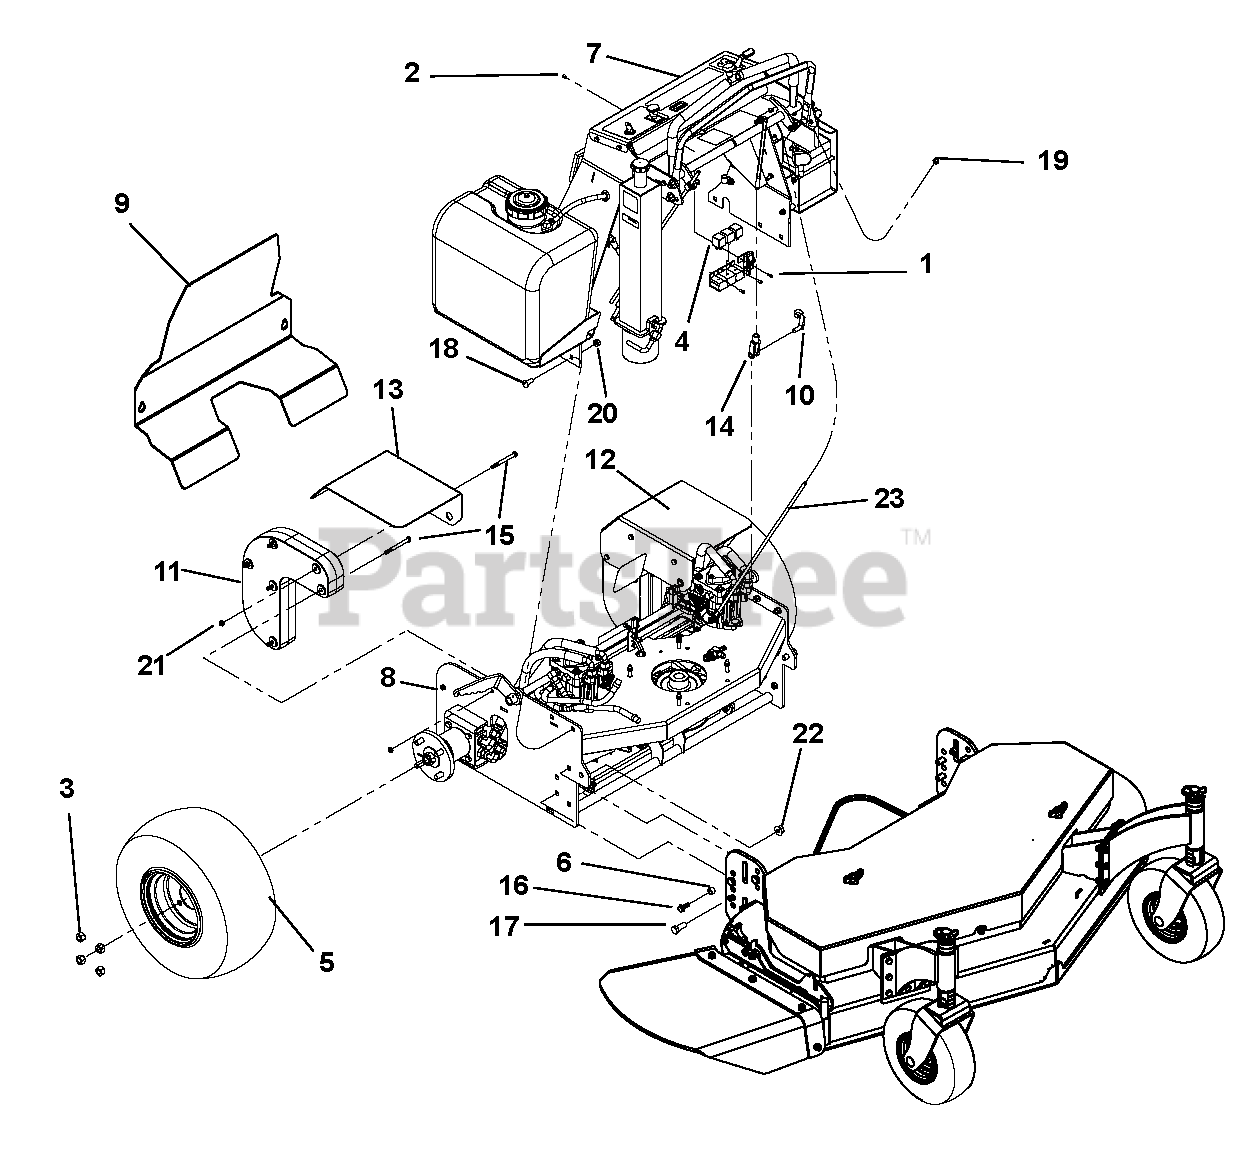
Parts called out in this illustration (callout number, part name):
1	Bolt, Hex 8-32 x .5
2	Nut, Locking, Nylon 8-32
3	Nut, Lug .5-20
4	Relay, ISO Mini Electric
5	Assembly, Tire/Wheel 18/8.5 x 8
6	Spacer, .625 x .120 x .400
7	Assembly, Console (See Console Components on page 23.)
8	Power Unit (See Engine, Hydraulic and Mainframe Assembly on page 10.)
9	Foot Guard w/Decals S/O
10	Pin, CVS SPG 3/8" Yoke
11	Weight, Cast Drilled
12	Fender, LH
13	Fender, RH
14	Yoke, 3/8-24 RH Adjustable
15	Bolt, .31-18 x 3.25 Grade 5
16	Bolt, .38-16 x 1.00, Washer Head Grade 8
17	Bolt, .50-13 x 1.25 Grade 5
18	Bolt, Round Head Square Neck .38-16 x 1.00
19	Nut, Hex .312-24
20	Nut, Locking, .375-16
21	Nut, Locking, Nylon .312-18
22	Nut, Locking .50-13
23	Control Rod
